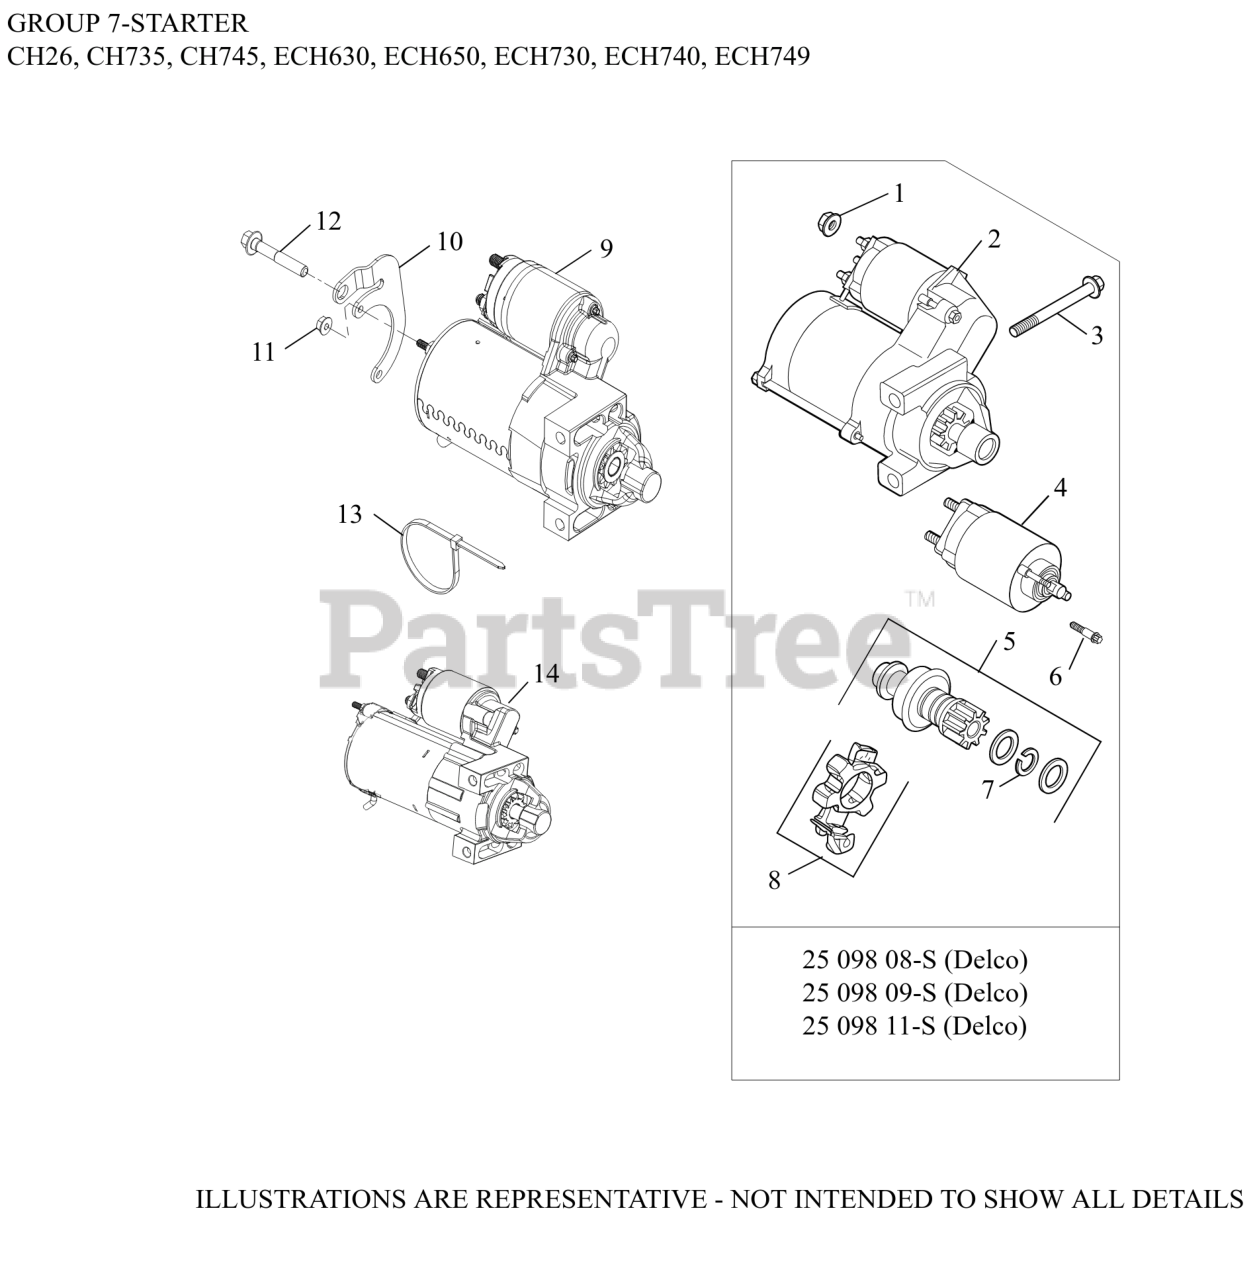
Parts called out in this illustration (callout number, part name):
1	NUT, FLG M8X1.25
2	STARTER, SOLENOID SHIFT-USE 25 098 11-S
2	STARTER,SOLENOID SHIFT-USE 25 098 11-S
2	ELECTRIC STARTER-USE 25 098 20-S
3	SCREW, FLG M8X1.25X80
4	SOLENOID, ASSEMBLY-USE 25 435 06-S
4	KIT, SOLENOID
5	KIT, STARTER PINION
6	SCREW, EXTERNAL TORX HEAD
7	RING, RETAINING-(#DSC)
8	KIT, BRUSH HOLDER
NI	SOLENOID-(#DSC)
